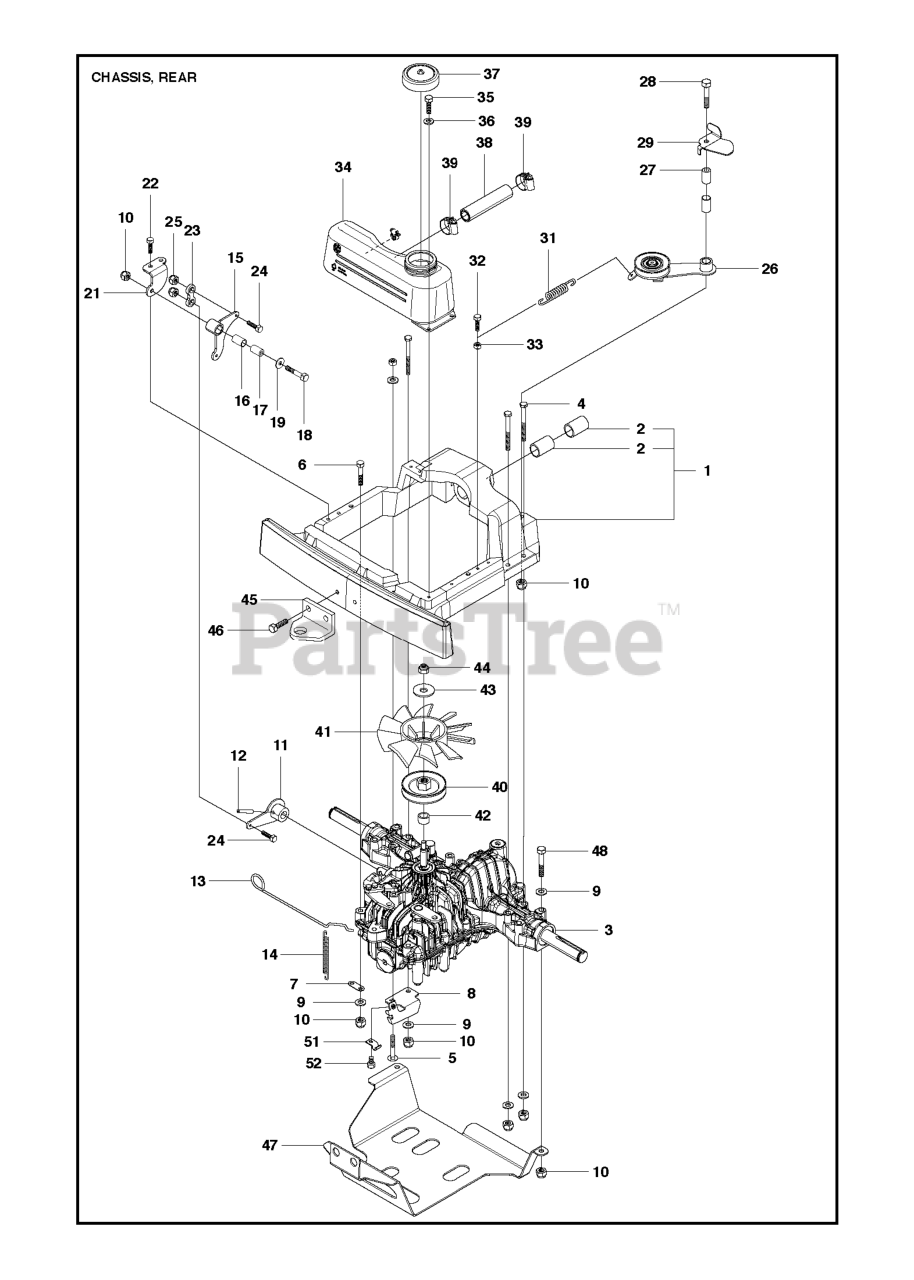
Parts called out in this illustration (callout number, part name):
9	WASHER BRB 8.4X17
10	LOCKNUT M8
18	SCREW
22	REPL BY 725 24 49-51
24	BOLT FLANGE - M6X20
25	LOCKNUT M8
34	EXPANSION TANK K664
35	BOLT FLANGE - M6X20
36	WASHER - 26X6.5X1.6
46	Screw M10x25
